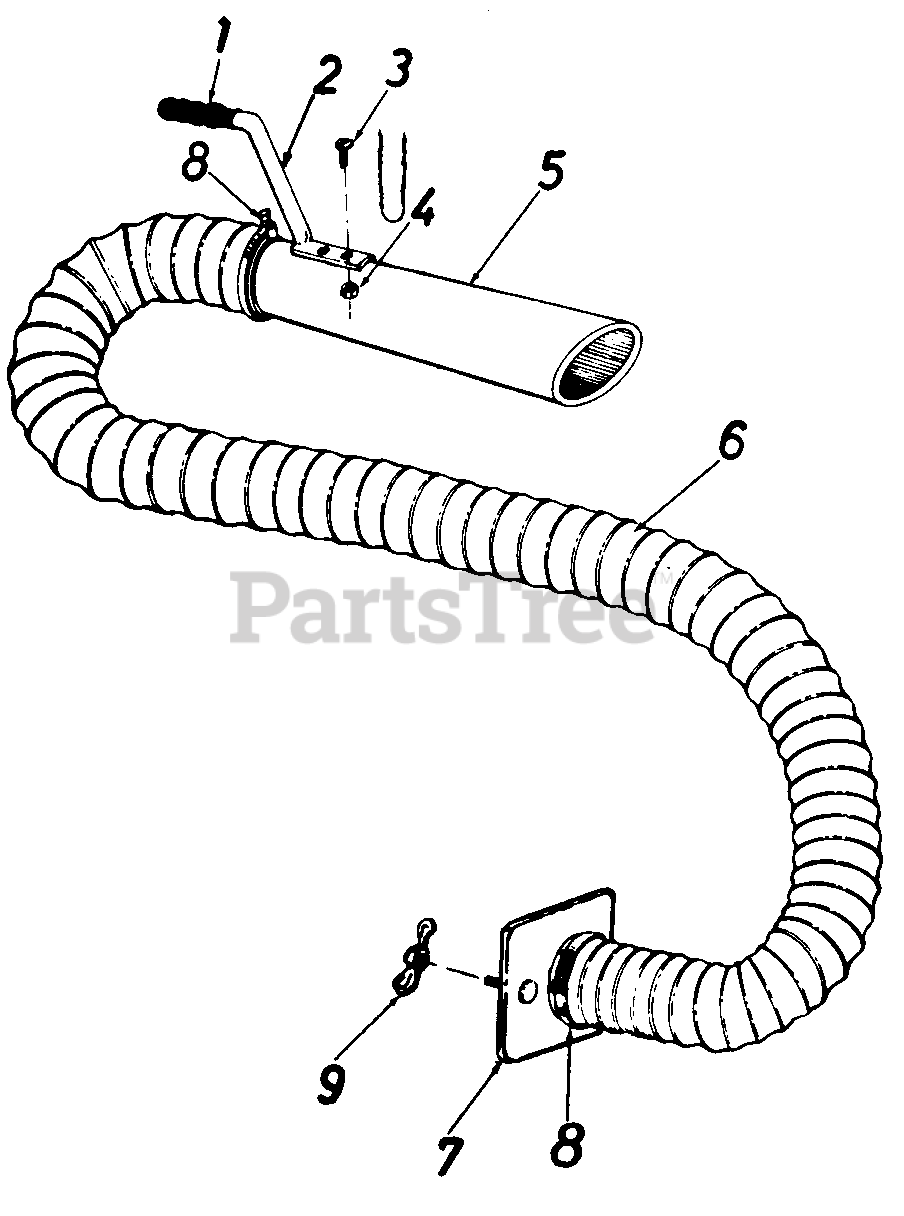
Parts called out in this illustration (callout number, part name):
1	Handle Grip
2	Handle
3	Truss Sems Scr. 10-24 x 1/2" Lg.*
4	Hex Nut 10-24 Thd.*
5	Hose Nozzle
6	Flexible Hose 4" Dia. x 10 Lg
7	Hose Adapter Plate
8	Hose Clamp-For 4" Dia. Hose
9	Wing Nut 1/4-20 Thd.
